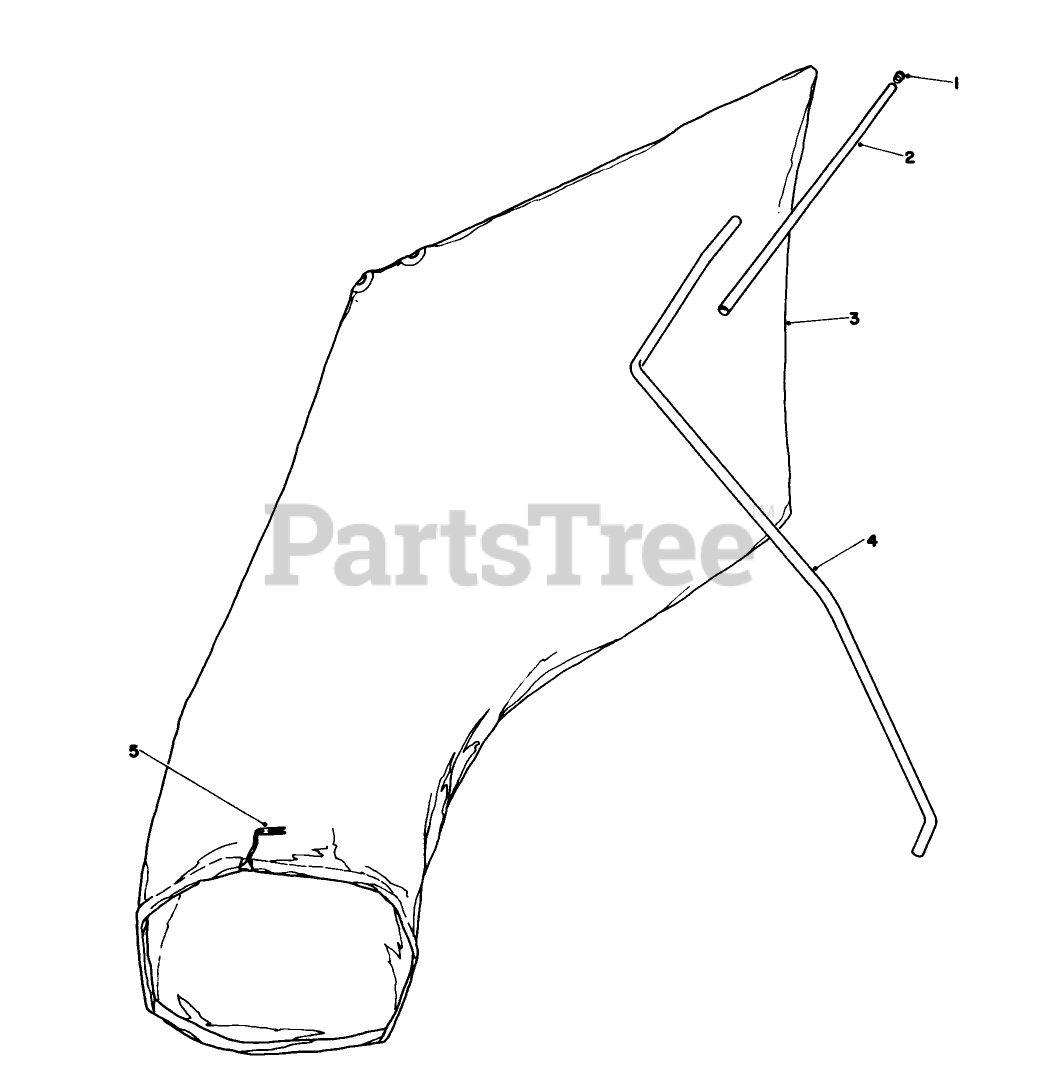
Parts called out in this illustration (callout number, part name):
2	BAG HANGER TUBE
3	Bag (Incl. Ref. #5)
4	HANGER ROD
5	BAG CORD FASTENER
